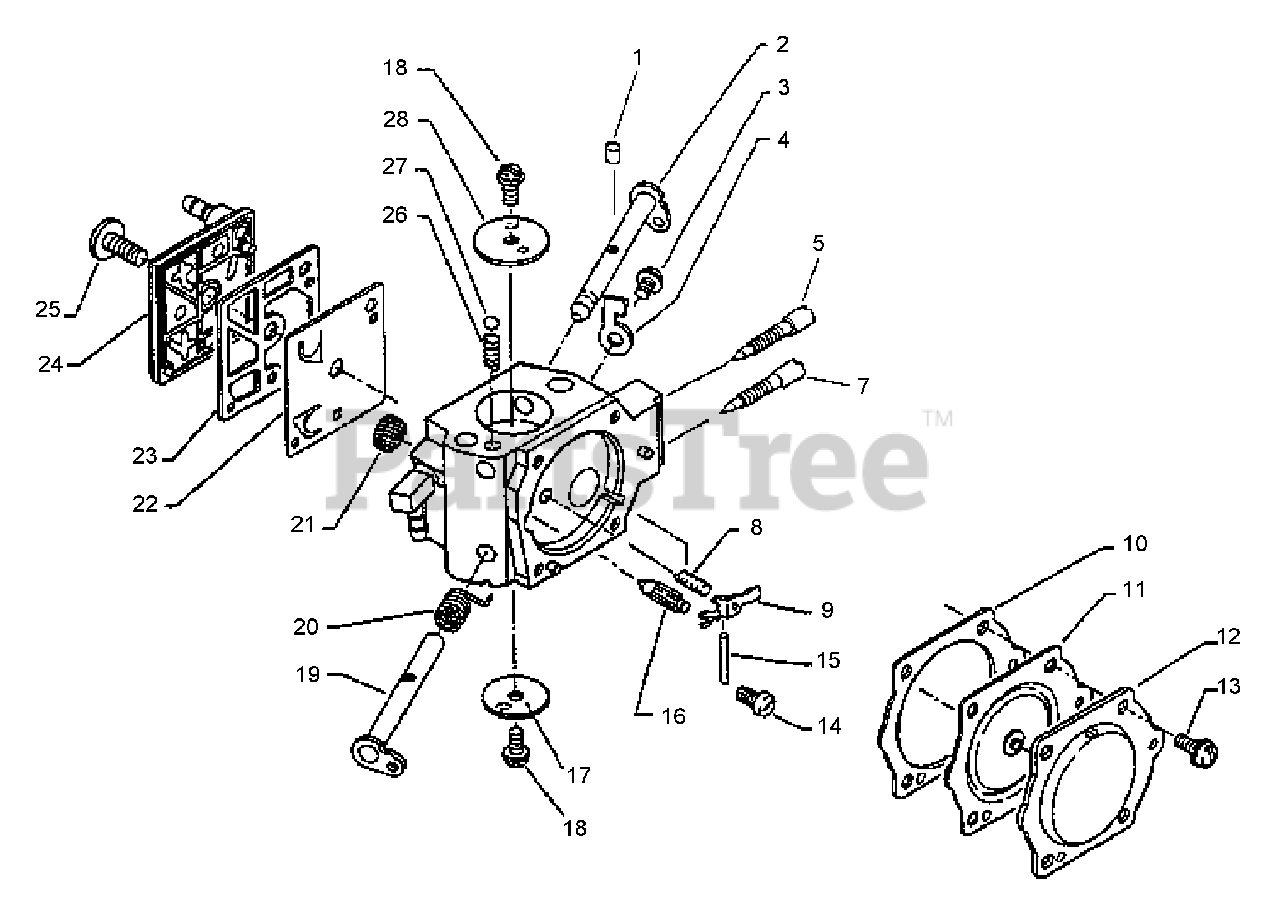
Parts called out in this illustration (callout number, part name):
1	PLUG, WELCH
2	SHAFT, CHOKE
4	STOP, THROTTLE
5	NEEDLE - HIGH SPEED
7	NEEDLE - LOW SPEED
8	SPRING, METERING LEVER
9	LEVER, METERING
10	GASKET, DIAPHRAGM
11	DIAPHRAGM, METERING
12	COVER, METERING
13	SCREW
14	SCREW, METERING LEVER PIN
15	PIN, METERING LEVER
16	VALVE, INLET NEEDLE
17	VALVE, THROTTLE
19	SHAFT, THROTTLE
20	SPRING, THROTTLE RETURN
21	STRAINER
22	DIAPHRAGM, PUMP
23	GASKET, PUMP
24	COVER, PUMP
25	SCREW, PUMP COVER
27	BALL, CHOKE
28	VALVE, CHOKE
